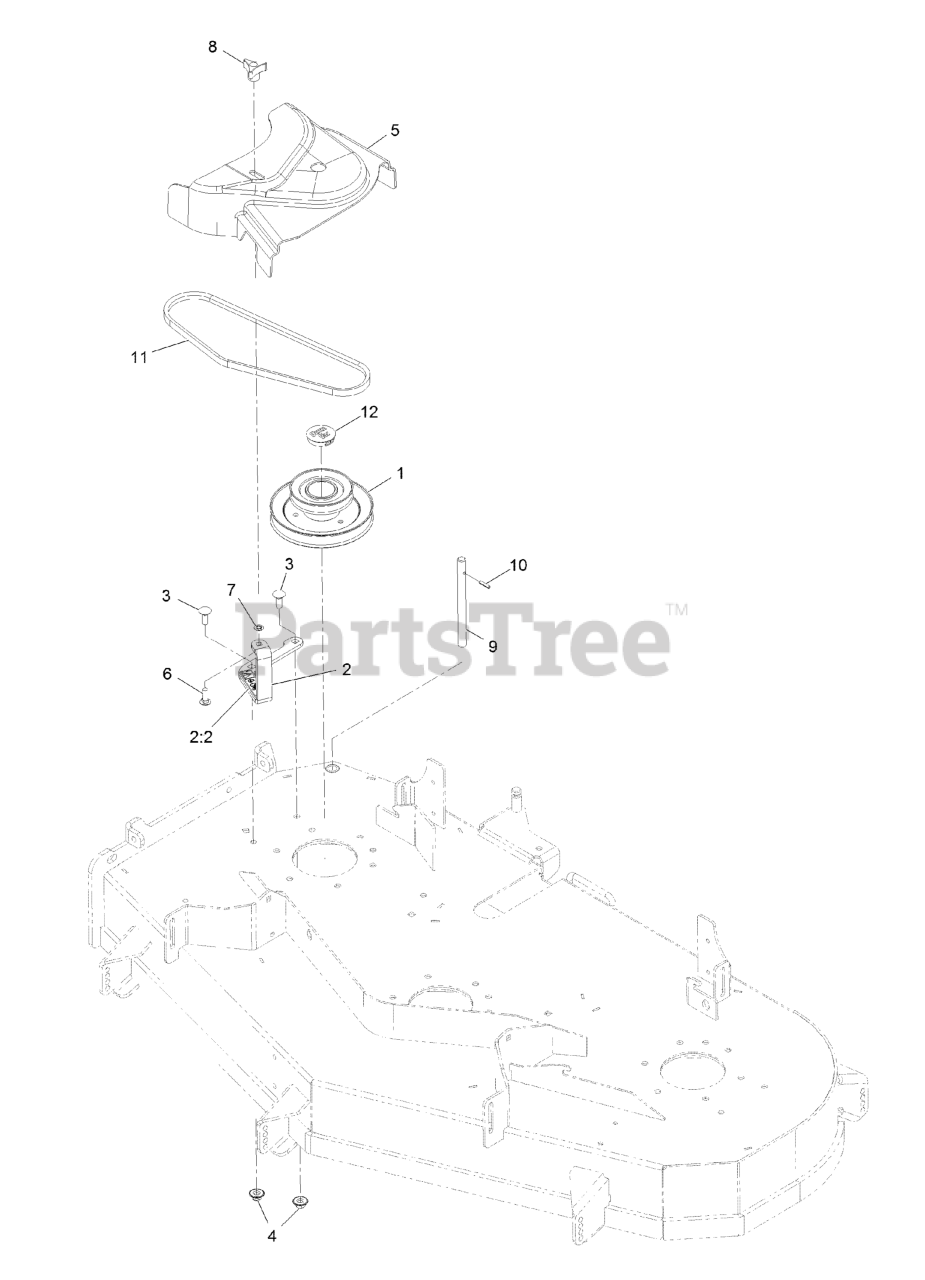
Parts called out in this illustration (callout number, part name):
1	JACKSHAFT,UV DRIVE 524 SPLINED
2	ASM-CVR BRKT W/DECAL
2:2	DECAL-DANGER
3	BOLT-CARR
4	Nut-Nyloc 3/8-16 Flg
5	COVER-BELT, UV 52 ENTRY
6	BOLT-CARR
7	RING-RETAINING, BOLT
8	KNOB-3 PRONG
9	SHAFT-CATCHER, GRASS
10	PIN-ROLL
11	BELT-BLOWER
12	PLUG, BLACK NYLON 1.75
